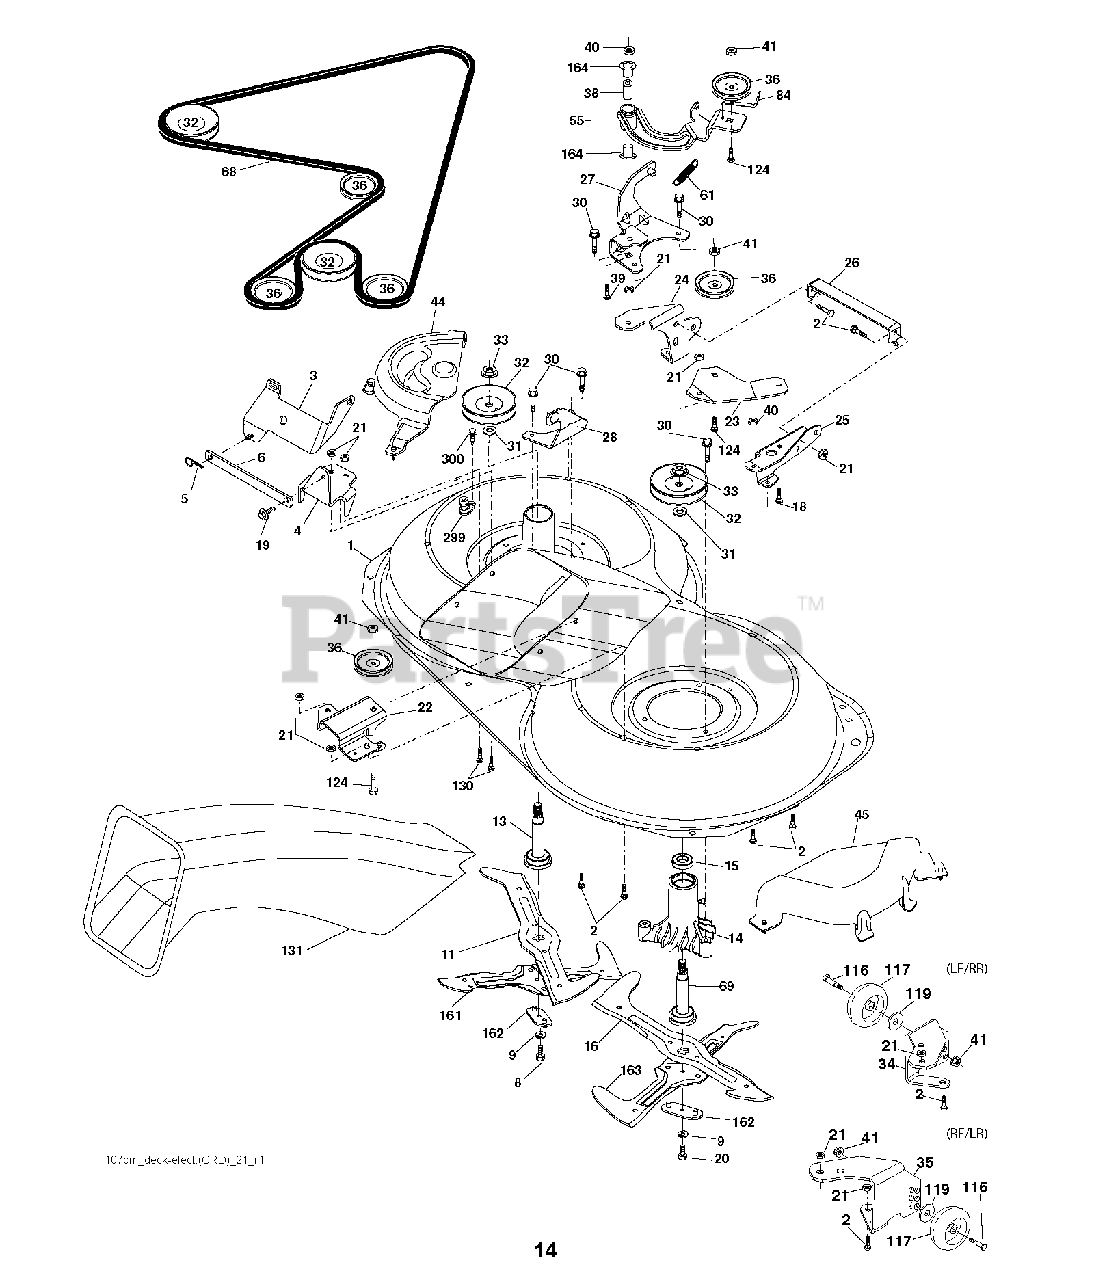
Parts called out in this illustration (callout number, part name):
2	BOLT
3	BRACKET.ASM.BAR.SWAY.CHASS
5	RETAINER-SPRNG RB
6	BAR SWAY
9	LOCKWASHER
11	BLADE.3N1.LH.CRD
13	SHAFT ASM VENT
14	HSG MANDREL
16	BLADE.3N1.RH.CRD
19	BOLT SHD 5/16-18
21	LOCKNUT
22	BRACKET
23	BRACKET
27	BRACKET
30	SCREW, WASHER HEAD
31	WASHER.SPACER.MANDREL
33	NUT.FLANGE.LOCK.TOP
36	PULLEY.IDLER.4.25
40	LOCKNUT
41	NUT LOCK FLG 3/8-16 UNC
55	ARM IDLER
68	HEX-BELT 107 MOWER
69	SHAFT.ASM.W/LWR.BRG.RH.THREAD
84	KEEPER, BELT IDLER
116	BOLT.SHOULDER.3/8-16X3-5/8
117	WHEEL. GUAGE RALLY
124	BOLT.3/8-16X1.50
131	CHUTE BAGGER
164	BRNG T
299	PORT.WASHOUT
